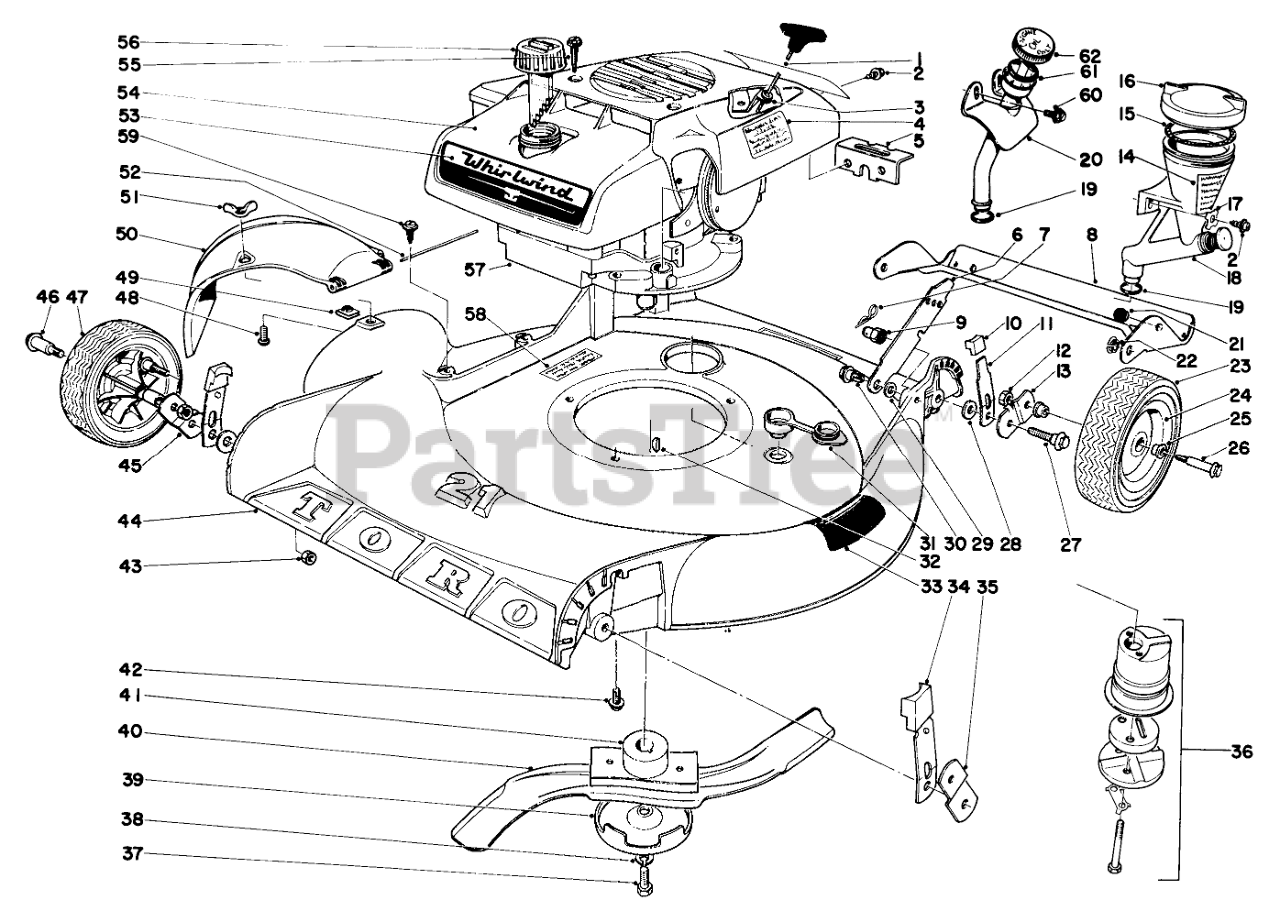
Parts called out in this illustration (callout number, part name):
1	Decal,Maintenance
2	SCREW-HWHTF
3	Bracket,Recoil
4	Decal,Start
5	Bracket
6	Latch
7	PIN-COTTER, HAIR
8	Safety Shield, Rear
9	Nut
11	Spring Arm
12	Nut
13	Pivot Arm
14	Decal, Reservoir
15	"O" Ring
16	Cap, Reservoir (Incl. Ref. #15)(Used on Model 19224)
17	Washer
18	Reservoir, Oil
19	O-RING
20	Oiler Tube
21	SKID BUTTON
22	Nyliner
23	8 TIRE
24	Wheel Assy. (Incl. Ref. 25)
25	Bushing
26	Wheel Bolt
27	Pivot Screw
28	WASHER-PIVOT
29	SPACER
30	SCREW-SHOULDER
31	Washer Plug
32	KEY-WOODRUFF
34	ARM KNOB
35	Pivot Arm
36	MUFFLER KIT
37	SPECIAL SCREW
38	WASHER-LOCK
39	ANTI-SCALP CUP
40	Blade
41	BLADE RETAINER WA
42	Screw
43	Nut
44	Housing
45	Pivot Arm
49	NUT-SPEED
50	Deflector
51	NUT-WING SPECL
52	HINGE PIN
53	Decal
54	Shroud
55	SCREW-HWH
56	Gas Cap
57	Engine
58	Decal
59	SCREW-HWHTF
61	O-Ring
62	Dipstick
